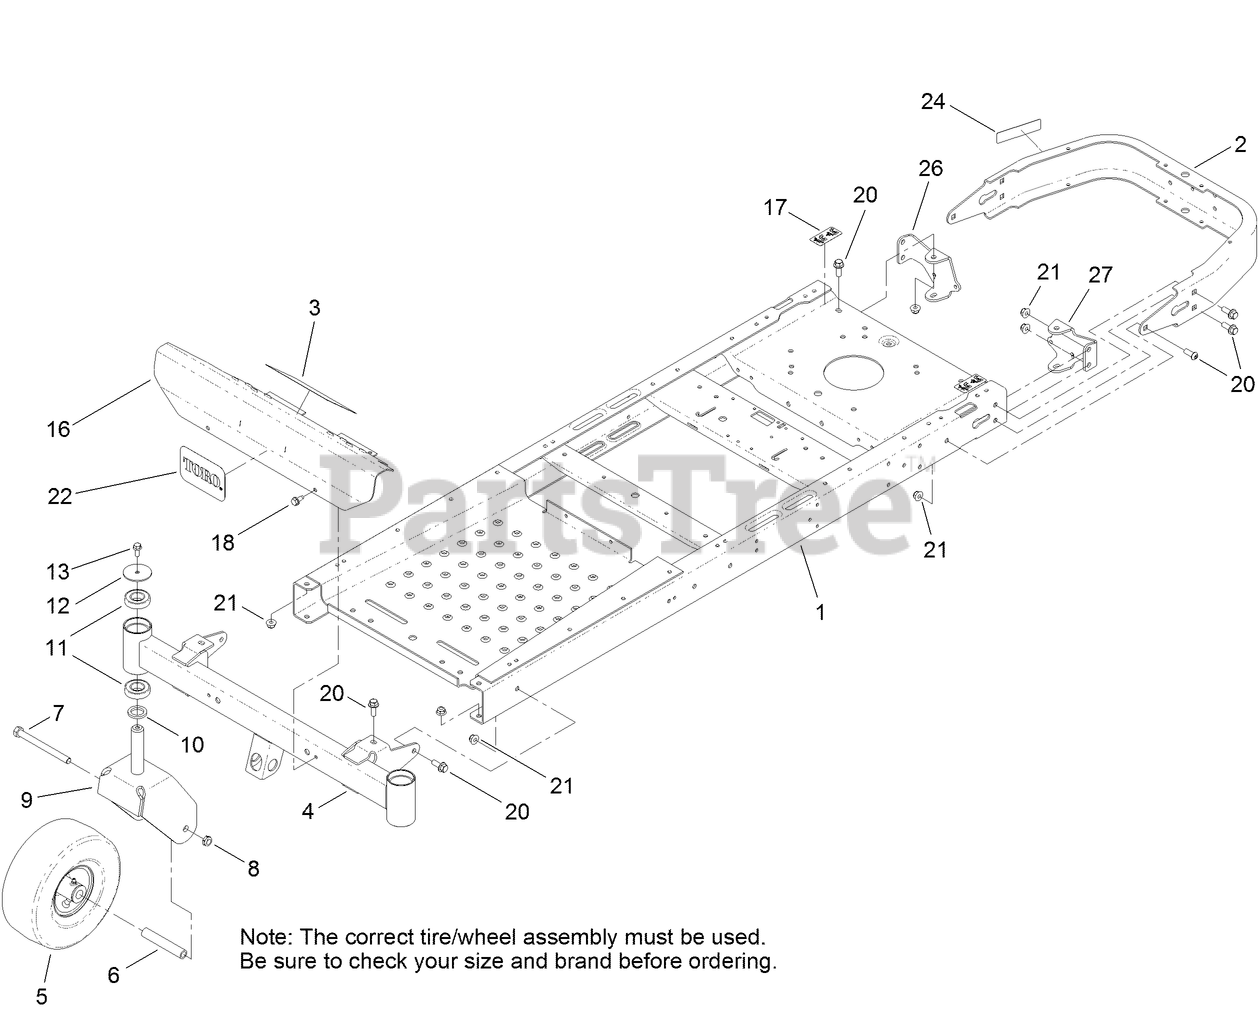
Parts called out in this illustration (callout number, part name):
2	BUMPER-REAR
4	AXLE-FRONT
5	CASTER WHEEL ASM (CST)
5	CASTER WHEEL ASM
6	BUSHING-SPANNER
7	SCREW-HH
8	NUT-HEX
9	FORK-CASTER
10	WASHER-THRUST
11	BEARING-BALL
12	WASHER
13	SCREW-HHF
17	DECAL-BYPASS
18	SCREW-HWHTF
20	SCREW-HHF
21	NUT-HF, NI
24	DECAL-ARRESTER, SPARK
26	MOUNT-HYDRO, REAR (RH)
27	MOUNT-HYDRO, REAR (LH)
